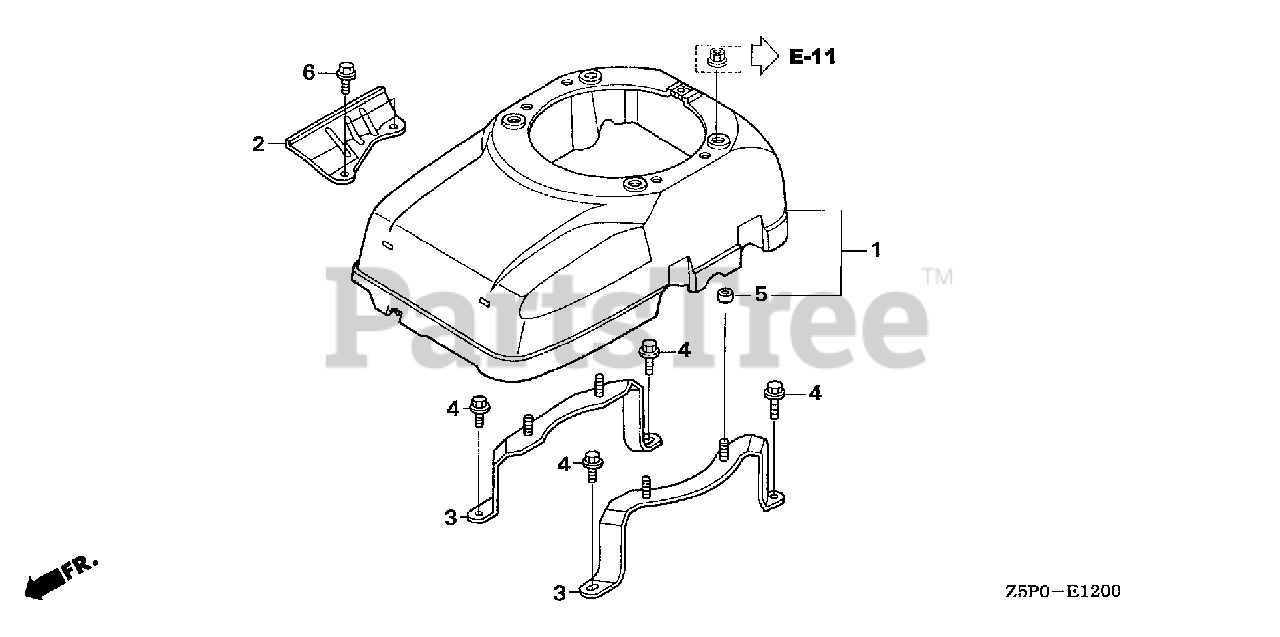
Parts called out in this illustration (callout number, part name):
1	COVER, FAN *R280* (POWER RED)
2	PLATE, SIDE
3	BRACKET, FAN COVER
4	BOLT, FLANGE (6X16) (CT200)
5	COLLAR, FAN COVER
6	BOLT, FLANGE (8X20)
